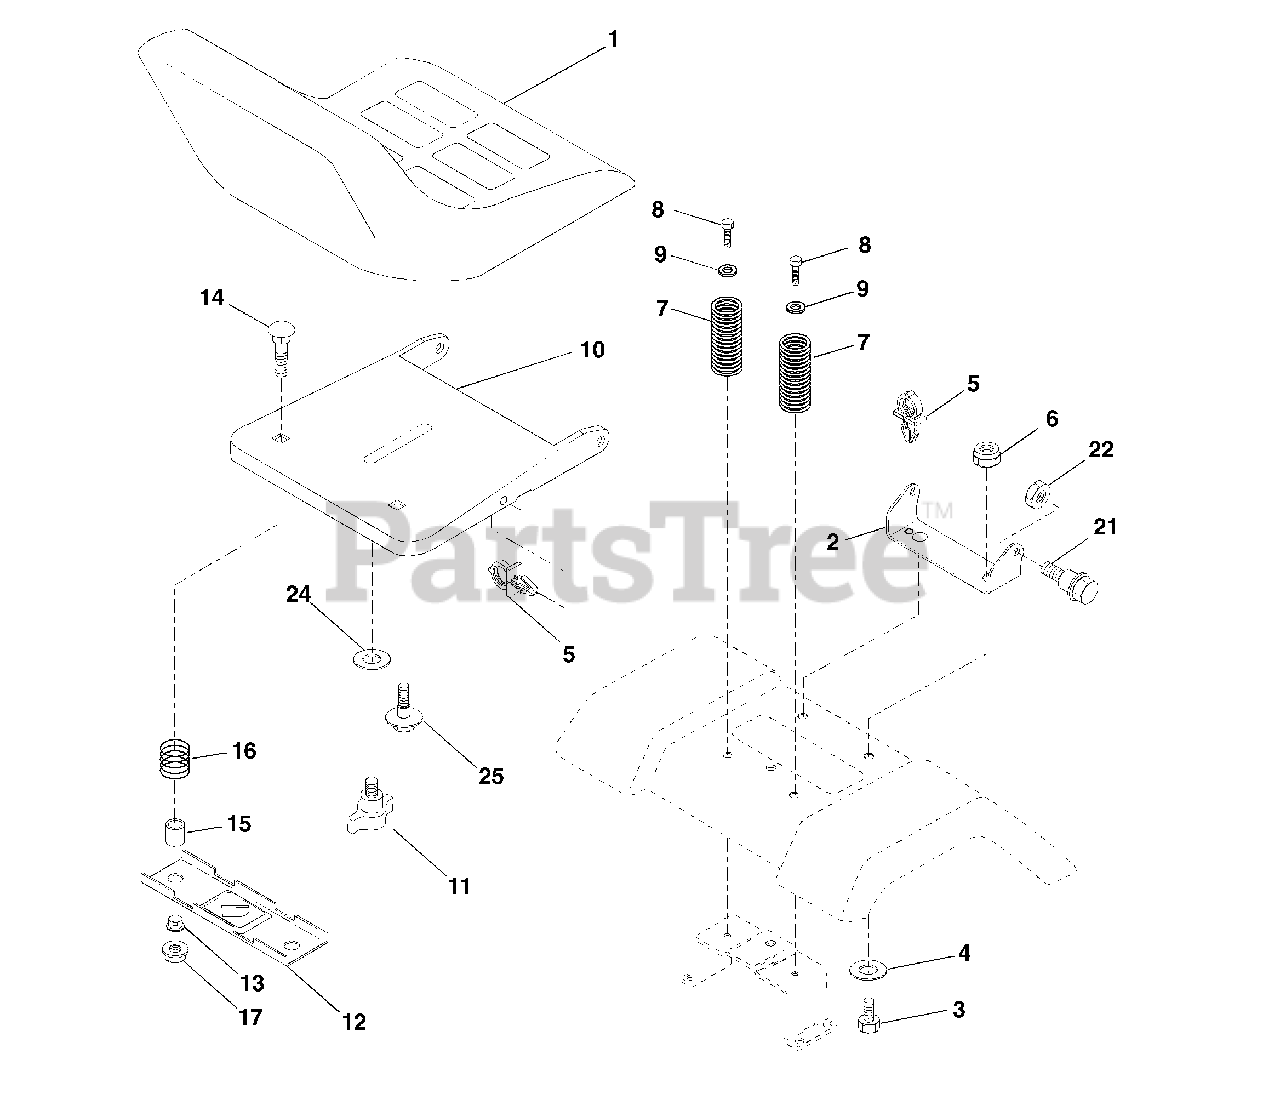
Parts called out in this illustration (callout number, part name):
1	Seat
2	Bracket Pivot Seat 8 720
3	Bolt Fin Hex 3/8-16 Unc X 1
4	Washer 13/32 X 1 X 10 Ga
5	Clip Push-In
6	Nut Hex w/Ins. 3/8-16 Unc
7	Spring Seat Cprsn 2 250 Blk Zi
8	Screw 3/8-16 X 1.5
9	Washer 13/32 X 1 X 14 Ga.
10	Pan Seat
11	Knob Seat
12	Bracket Mounting Switch
13	Bushing Snap Blk Nyl 50 Id
14	Bolt Rdhd Sqnk 1/4-20x1-1/2
15	Spacer Split 28x 88
16	Spring Cprsn
17	Nut Lock 1/4 Lge Flg Gr 5 Zinc
21	Bolt Shoulder 5/16-18 Unc
22	Nut Hex Lock W/Ins 5/16-18
24	Washer 17/32 X 1-3/16 X 12 Ga.
25	Bolt Shoulder 5/16-18 X 62
